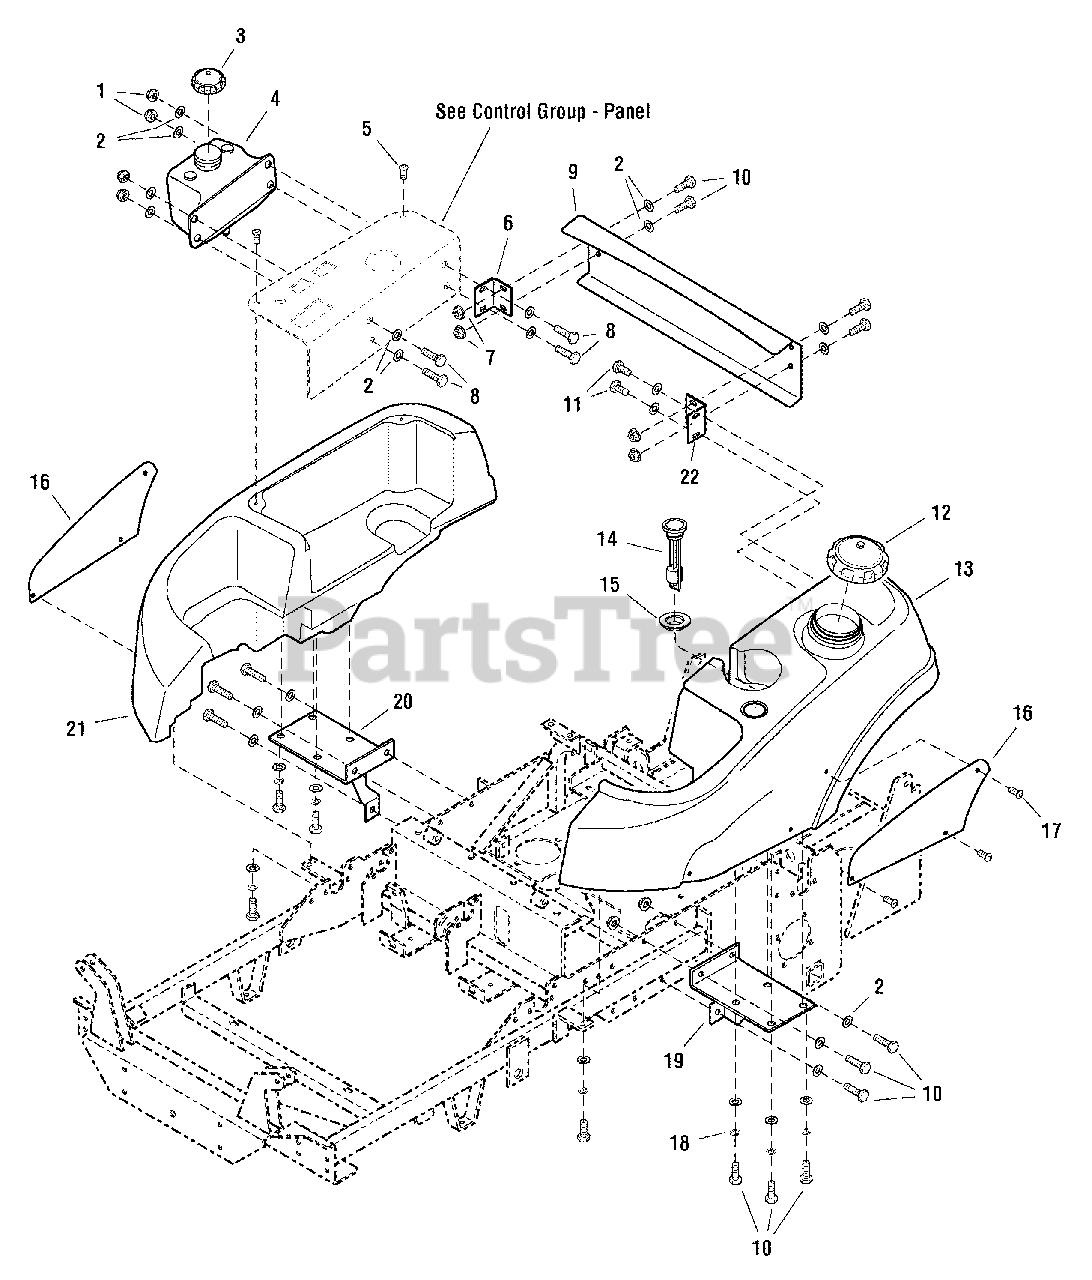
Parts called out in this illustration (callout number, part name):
1	NUT, Hex Nylon Lock, 5/16-18
2	WASHER, SAE, 5/16
4	HYDRAULIC TANK
5	CAPSCREW, Button Allen Head, 1/4-20 x 3/4
6	BRACKET, Rear Support, RH, Orange
6	BRACKET, Rear Support, RH, Red
7	NUT, Hex Serrated Flange, 5/16-18
8	CAPSCREW, Hex Head, 5/16-18 X 1
9	PLATE, Rear Plate Support, Orange
9	PLATE, Rear Plate Support, Red
10	CAPSCREW, Hex Head, 5/16-18 X 3/4
11	CAPSCREW, Hex Head, 5/16-18 X 5/8
12	CAP, Fuel
13	FUEL TANK ASSEMBLY, LH
14	GAUGE, Fuel
16	TANK BADGE, Orange
16	TANK BADGE, Red
17	CAPSCREW, Button Allen Head, #10-24 X 3/8
18	WASHER, Lock, 5/16
19	MOUNT, Fuel Tank, LH, Orange
19	MOUNT, Fuel Tank, LH, Red
20	MOUNT, Fuel Tank, RH, Orange
20	MOUNT, Fuel Tank, RH, Red
21	FUEL TANK, RH
22	BRACKET, Rear Support, RH, Orange
22	BRACKET, Rear Support, RH, Red
